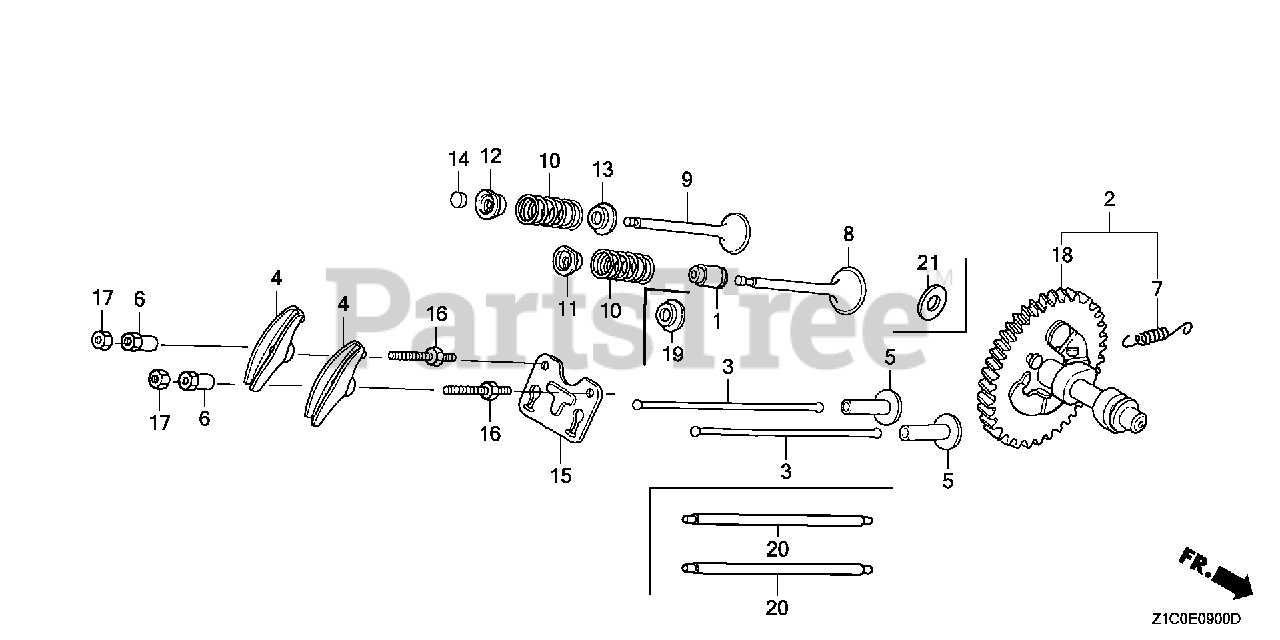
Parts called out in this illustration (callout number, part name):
1	SEAL, VALVE STEM
2	CAMSHAFT ASSY.
4	ARM, VALVE ROCKER
5	LIFTER, VALVE
6	PIVOT, ROCKER ARM
7	SPRING, WEIGHT RETURN
8	VALVE, IN.
9	VALVE, EX.
10	SPRING, VALVE
11	RETAINER, IN. VALVE SPRING (EXHAUST SIDE)
12	RETAINER, EX. VALVE SPRING
13	SEAT, VALVE SPRING
14	ROTATOR, VALVE
15	PLATE, PUSH ROD GUIDE
16	BOLT, PIVOT (8MM)
17	NUT, PIVOT ADJ.
